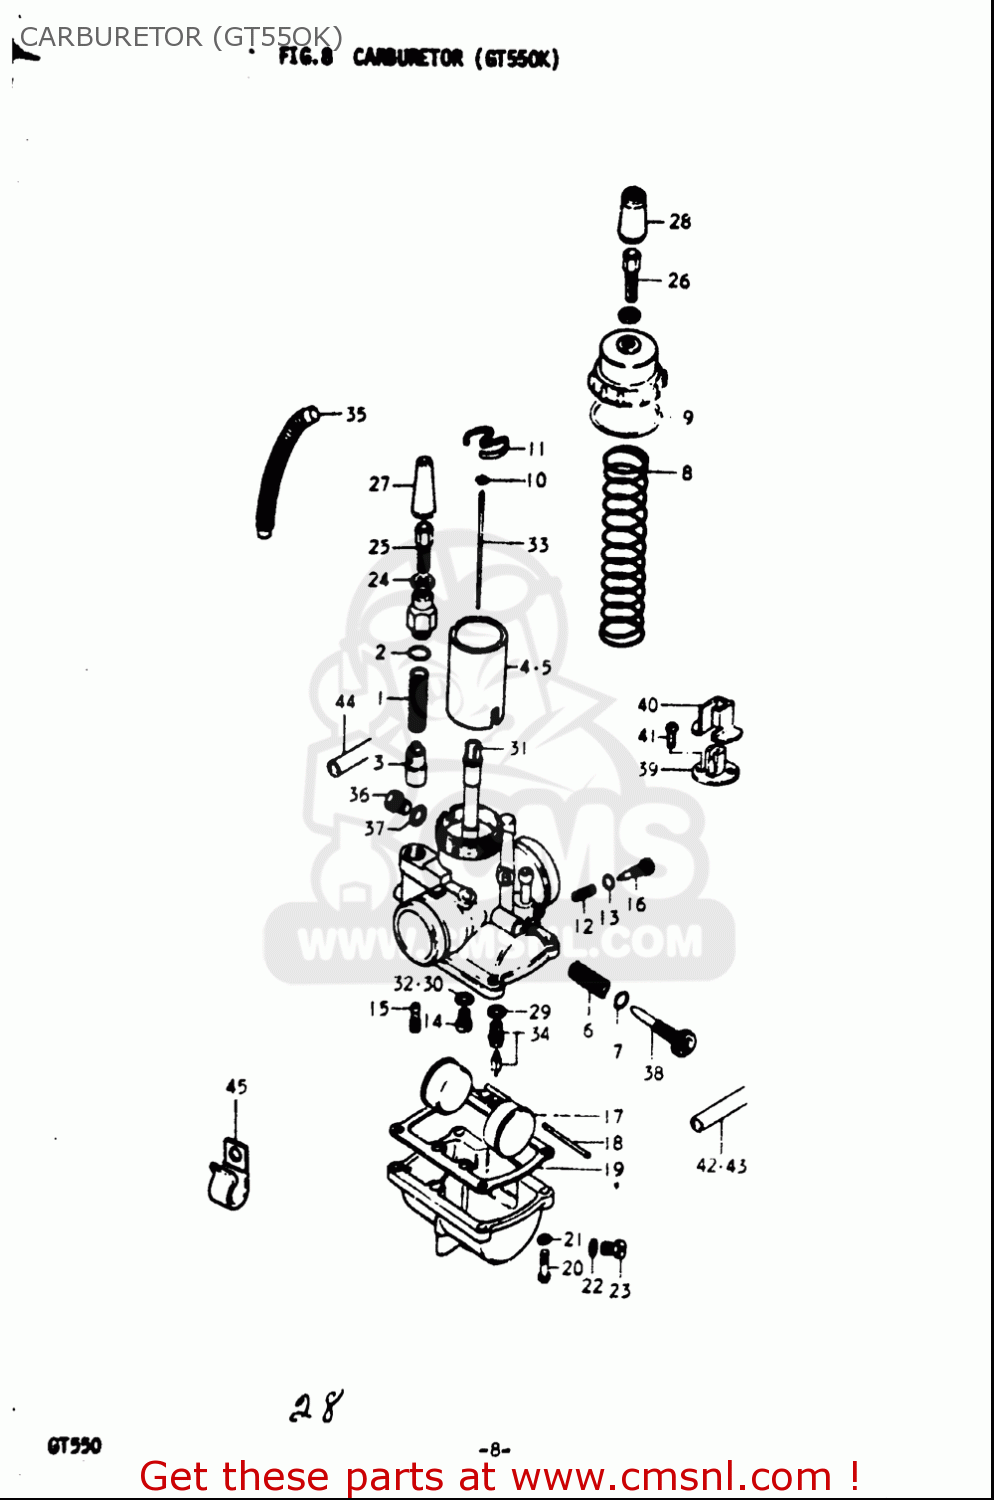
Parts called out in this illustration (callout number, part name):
1	SPRING
3	PLUNGER,STARTER
6	SPRING,THROTTLE SCREW
7	O RING
10	CLIP
11	SEAT,THROTTLE VALVE SPRING
12	SPRING
13	O RING
14	JET,MAIN(95)
15	JET,PILOT(25)
16	SCREW,PILOT AIR
17	FLOAT
18	PIN,FLOAT
19	GASKET,FLOAT CHAMBER (NAS)
20	SCREW 4X16
21	WASHER,LOCK
22	GASKET,DRAIN,PLUG (NAS)
23	PLUG
24	NUT
25	ADJUSTER,CABLE
27	CAP,RUBBER
29	GASKET,VALVE SEAT (NAS)
30	WASHER
34	VALVE ASSY,NEEDLE
36	BOLT
37	GASKET,THRO VALVE INSPECTION (NAS)
39	CONNECTOR
41	SCREW
